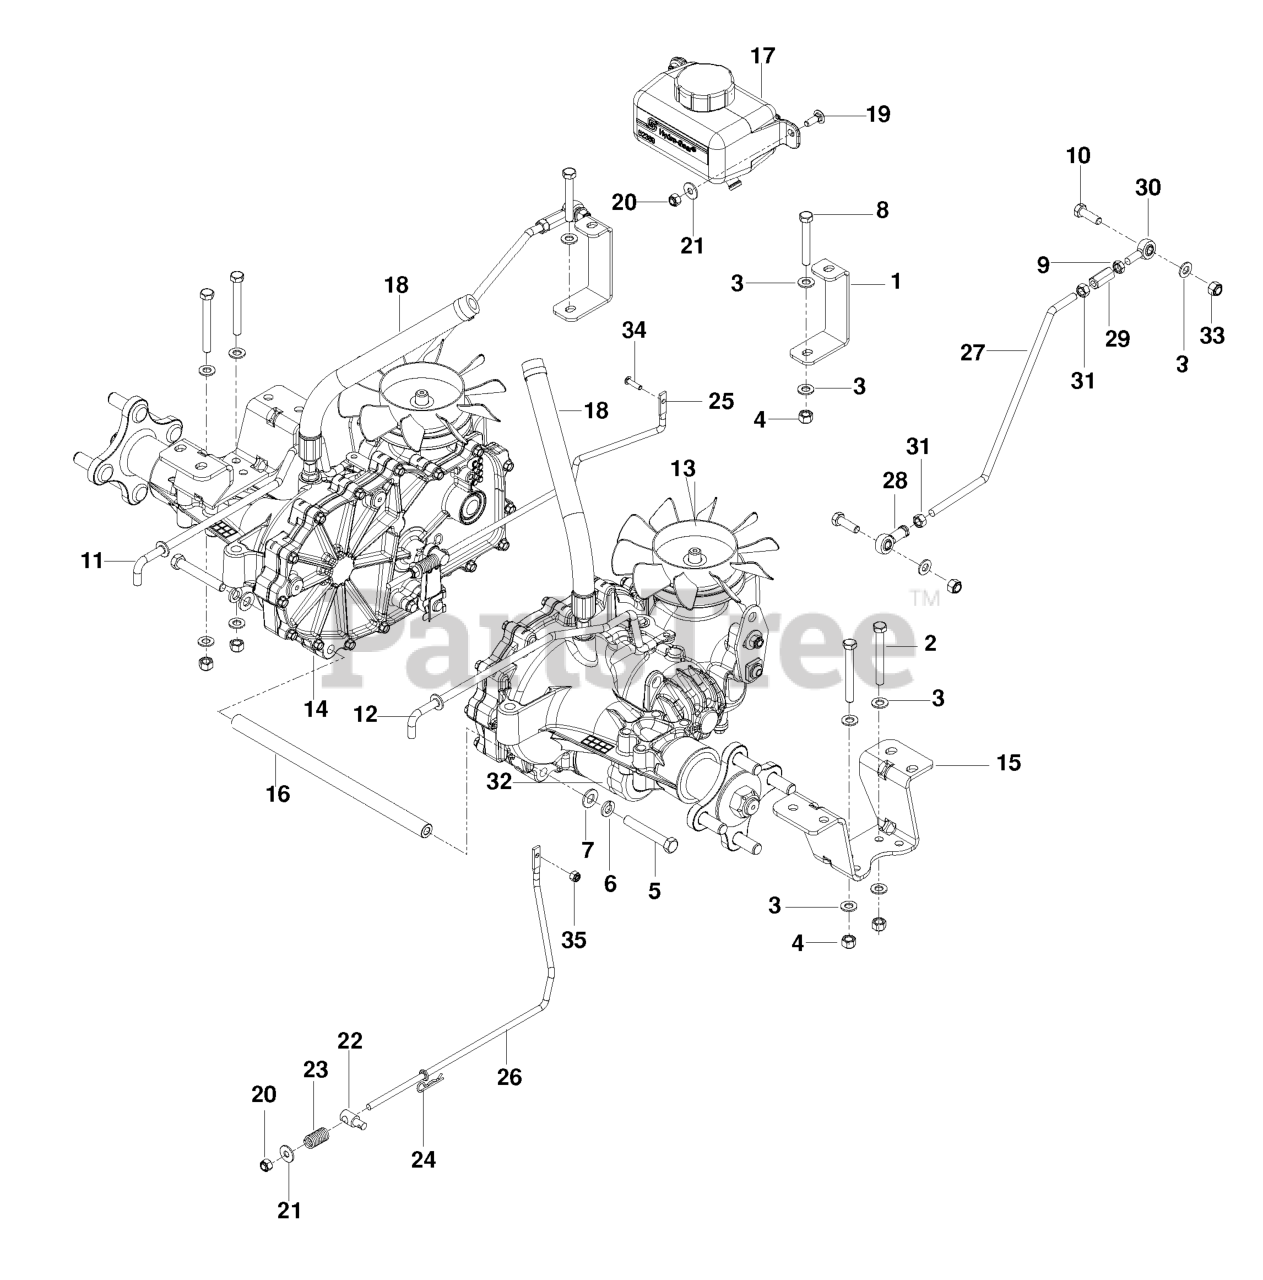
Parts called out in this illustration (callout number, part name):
1	SUPPORT.FRONT.TRANS.BLACK.
2	HCS 5/16C X 2-3/4
3	FLAT WASHER 5/16 SAE
4	NUT 5/16 NYLOC
5	HCS 3/8C X 2 1/2
6	SLW 3/8 STD
7	WASHER 3/8 SAE FLAT
9	NUT 5/16F LEFTHAND
10	HCS 5/16C X 1
11	ROD, BYPASS, RT
12	ROD, BYPASS, LT
13	HG_TRANS, ZT-2800 RT
14	HG_TRANS, ZT-2800 LEFT
15	EZT MOUNT, REAR, BLACK
16	SPACER TUBE, EZT, 11.08
17	HG_EXPANSION TANK W/CAP 71354
19	RHSNB 1/4C X 3/4
20	NUT.1/4-20.HEX.NYLOC.ZD
21	WASHER 1/4 FLAT
22	BRAKE SWIVEL
24	HAIRPIN #2
25	LINKAGE.BRAKE.LT
26	LINKAGE, BRAKE RT
27	ROD, MOTION CONTROL
28	RH ROD END
29	ROD END COUPLER
30	RP.ROD.END.LH
32	HG_FILTER, ZT4800 52114
33	5/16-18 THIN PROF NY
34	SCR #10-24 X 3/4
35	NUT 10-24 NYLOC
